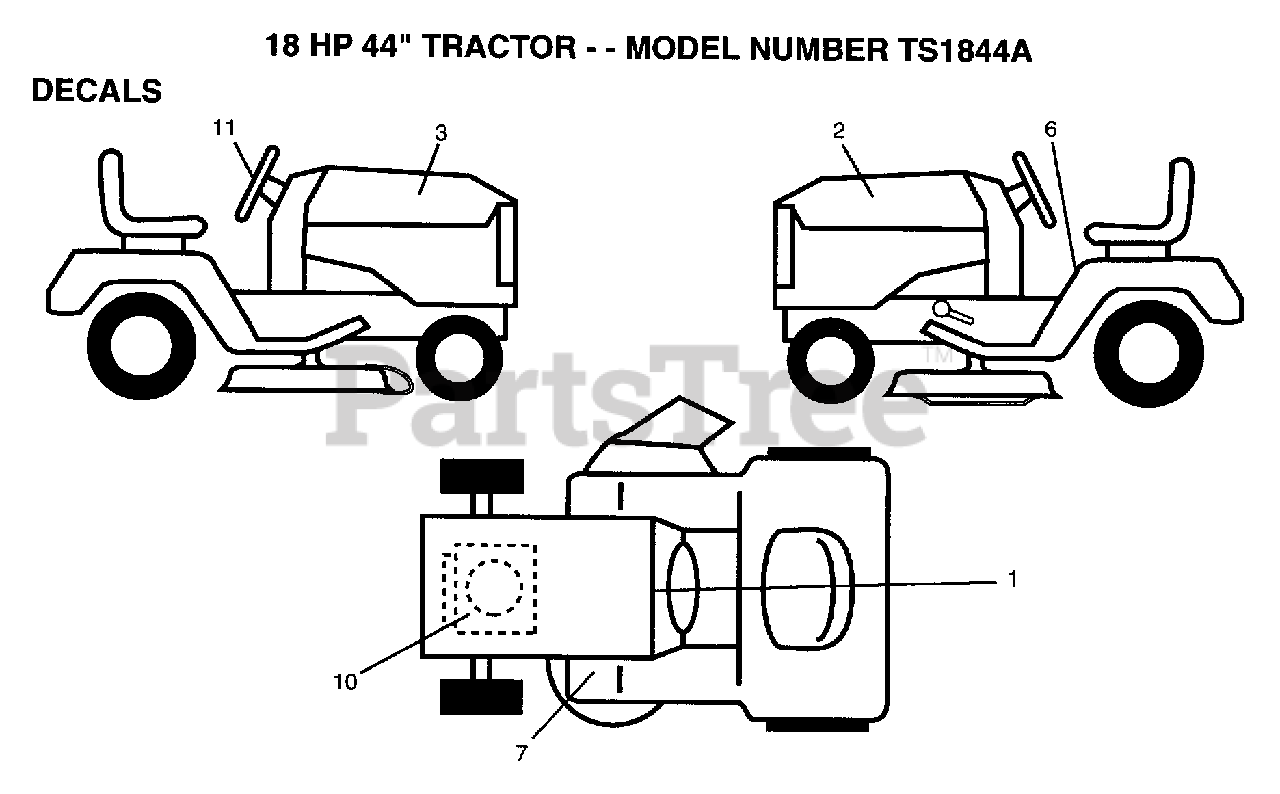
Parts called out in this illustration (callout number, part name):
1	DECAL.DASH.INST.
2	DECAL.HOOD.LH
6	DECAL
10	"DECAL,HP ENGINE"
11	DECAL.CAP.WHEEL
